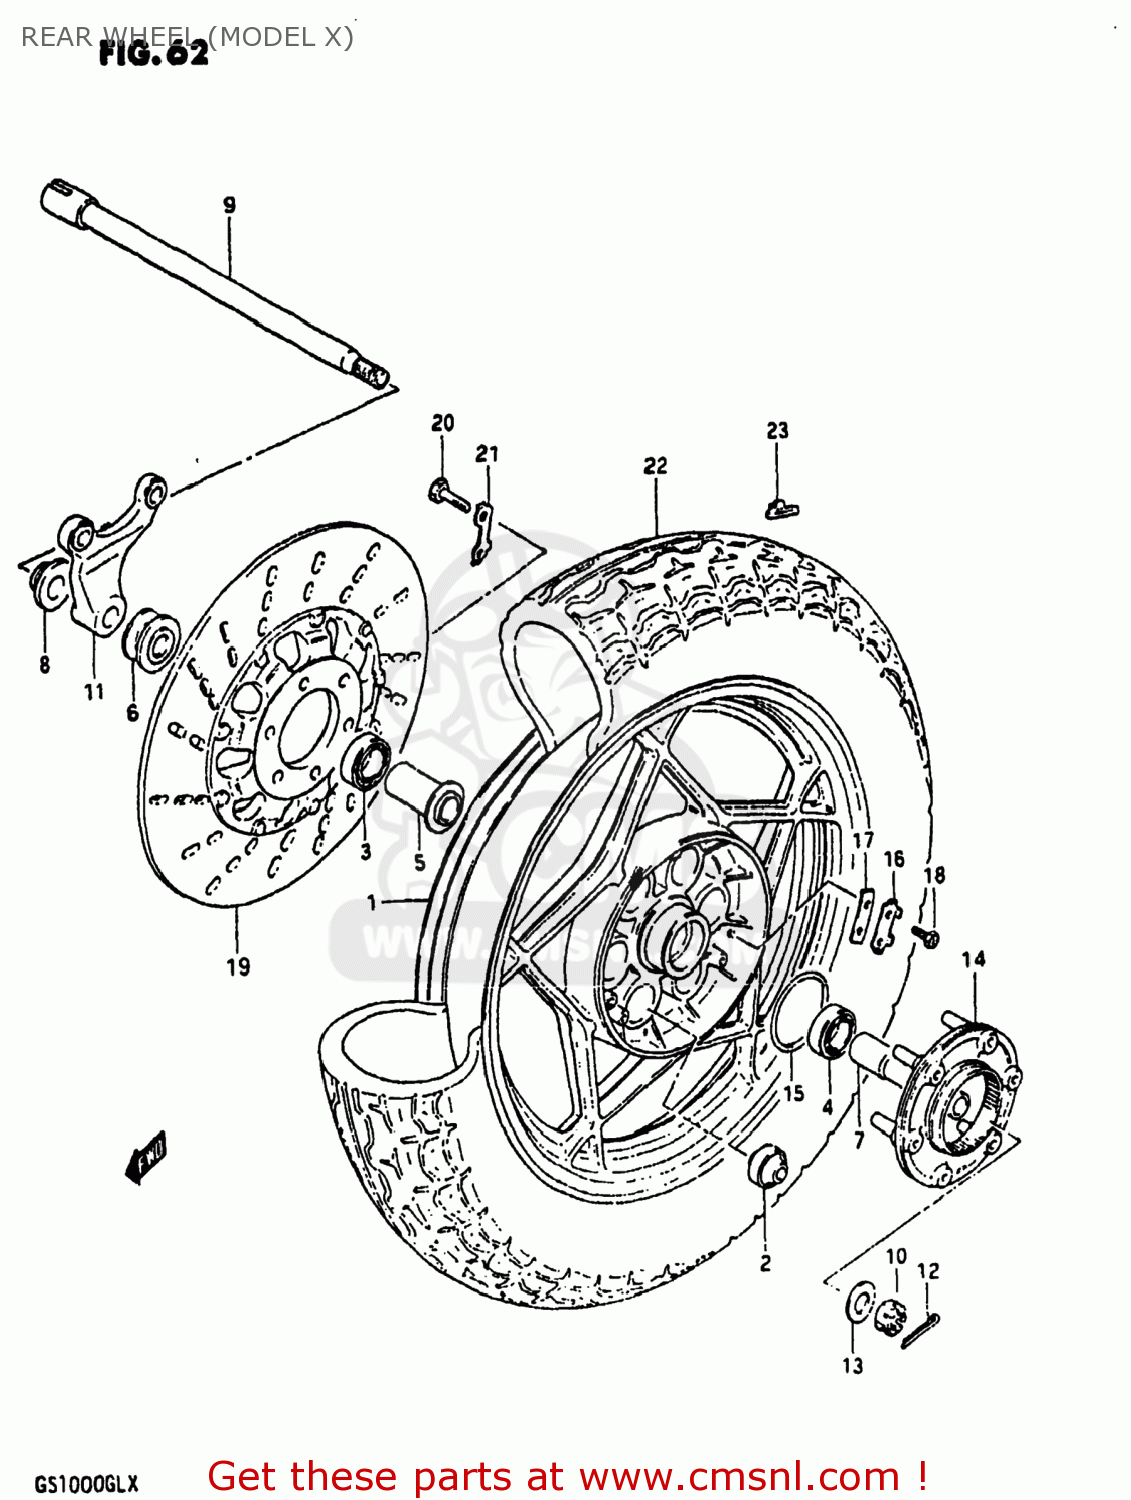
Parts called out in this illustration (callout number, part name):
1	WHEEL SET,REAR
2	BUSH
3	BEARING
4	BEARING
5	SPACER,REAR HUB BEARING
6	SPACER,REAR AXLE
7	SPACER,REAR AXLE,LEFT
8	SPACER,REAR AXLE,RIGHT
9	AXLE,REAR
10	NUT
11	BRACKET,RR,CALIPER
12	PIN,COTTER
13	WASHER (17.5X36X3.2)
14	JOINT ASSEMBLY,REAR HUB DRUM
15	O RING(D:2.1,ID:65)
16	WASHER (T:1.0)
17	WASHER,THRUST(T:1.6)
18	SCREW
19	DISC,RR BRAKE
20	BOLT(8X25)
21	WASHER
22	TIRE
23	BALANCER,WHEEL
